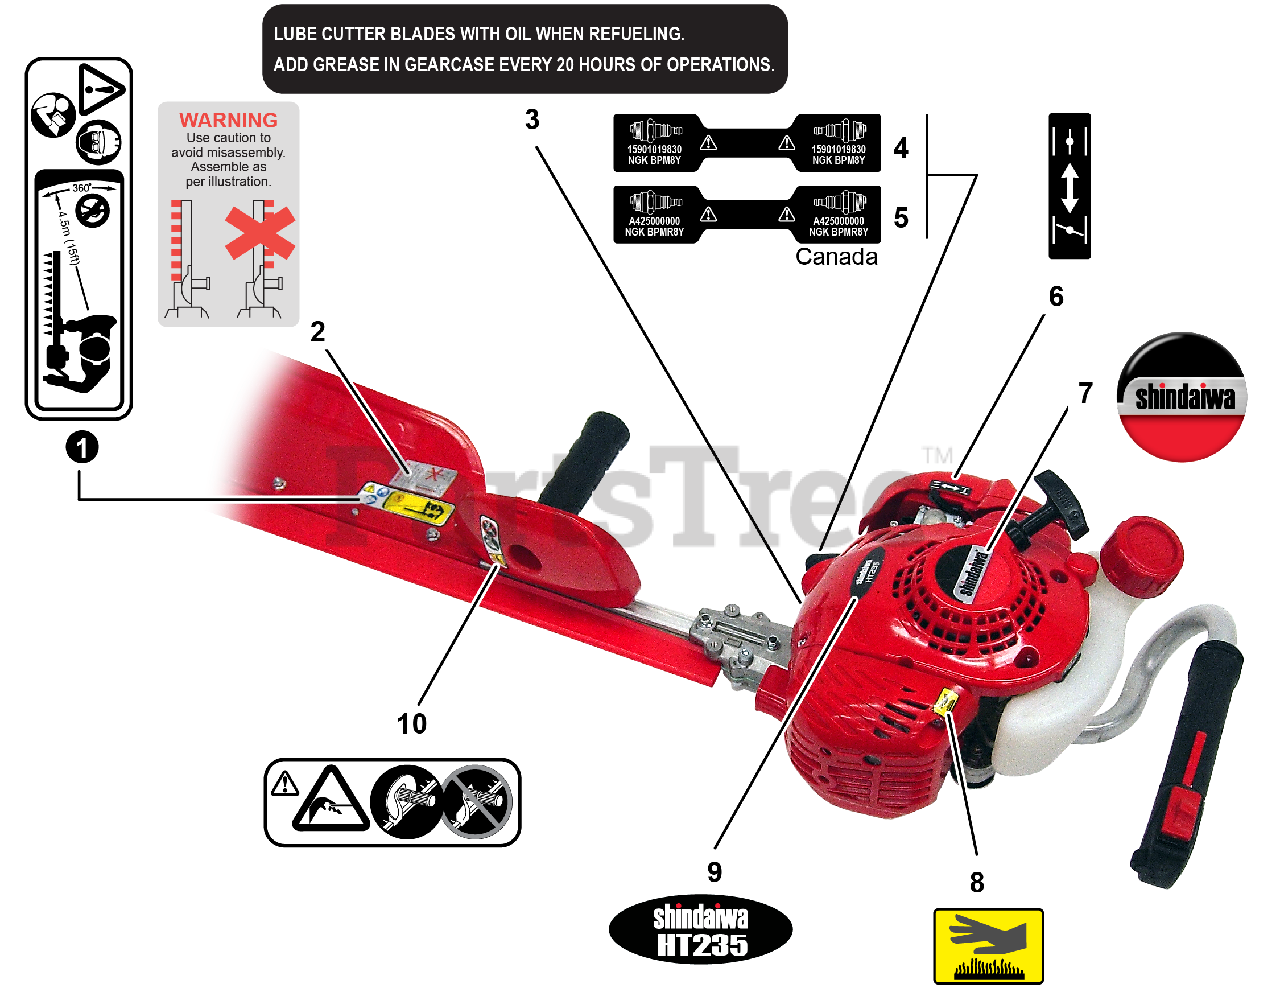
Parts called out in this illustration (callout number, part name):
1	LABEL, CAUTION
2	LABEL, WARNING
3	LABEL, LUBE BLADES
4	LABEL, SPARK PLUG - BPM8Y
5	LABEL, SPARK PLUG - BPMR8Y
6	LABEL, CHOKE
7	LABEL, shindaiwa
8	LABEL, CAUTION - HOT
9	LABEL - MODEL HT235
10	LABEL, CAUTION - ISO
